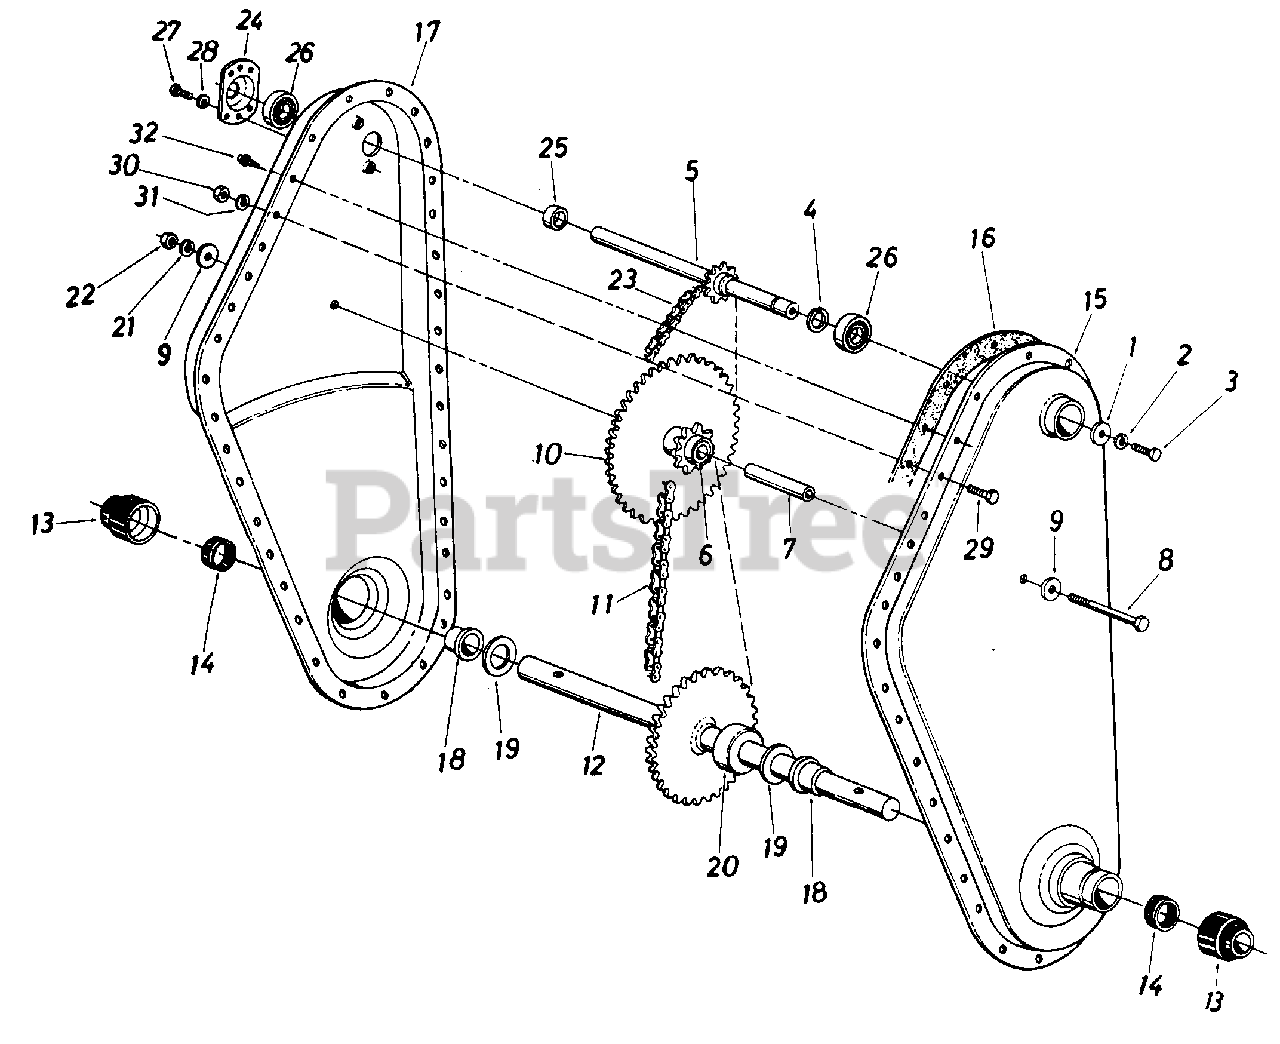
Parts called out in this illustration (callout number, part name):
1	Fl-Wash. 1/4" I.D. x .93" O.D. x .1 20
2	L-Wash. 1/4" I.D.
3	Hex Bolt 1/4-28 x .62" Lg. wlPatch
4	External Snap Ring-5/8" Dia.
5	Input Shaft Ass'y.
6	Bearing 5/8" I.D. x 3/4" O.D. x 1.860" Lg.
7	Sprocket Hub Tubing 3/8" I.D. x 5/8" O.D. x 1.90
8	Hex Bolt 3/8-24 x 2.75" Lg.
9	Fl-Wash. 3/8" I.D. x 1.25" O.D. x .10
10	Sprocket Ass'y.
11	#50 Chain 5/8" Pitch x 46 0 Links Endless
12	Tine Shaft Ass'y.
13	Dust Cup
14	Seal Ring Single Lip, Spring less
19	Fl-Thrust Wash. 1.0" I.D. x .03 Thk.
20	Step Spacer
21	L-Wash. 3/8" I.D.
22	Hex Nut 3/8-24 Thd.
23	#35 Chain 3/8" Pitch x 52 0 Links Endless
24	Bearing Housing 1.38" I.D.
25	Spacer
26	Ball Bearing .625" I.D. x 1.38 " O.D. x .437
27	Hex Wash. SF-Tap Scr. 1/4-20 x.50" Lg.
28	L-Wash. 1/4" I.D.
29	Hex Bolt 5/16-18 x .75" Lg.
30	Hex Nut 5/16-18 Thd.
31	L-Wash. 5/16" I.D.
32	Hex Wash. SF-Tap Scr. 1/4-20 x.50" Lg.
